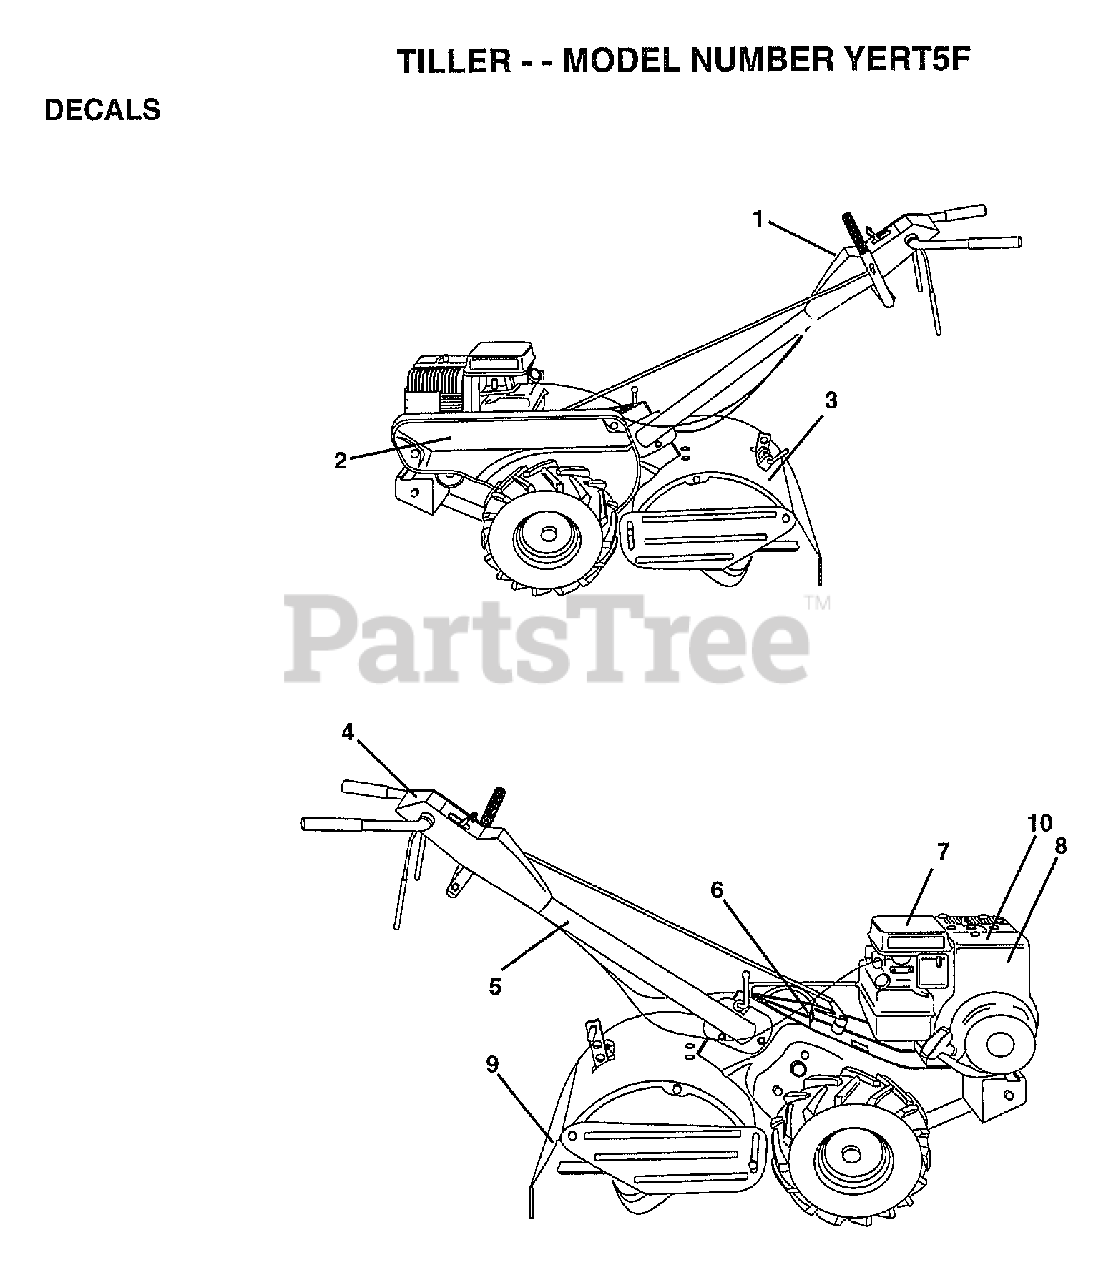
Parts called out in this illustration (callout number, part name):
1	DECAL.PNL.CONTROL
2	DECAL.LOGO.
4	DECAL.INSTRUCTION
5	DECAL TI
7	DECAL TI
8	DECAL, BRIGGS & STRATTON
10	DECAL.EURO.ST.CE.
